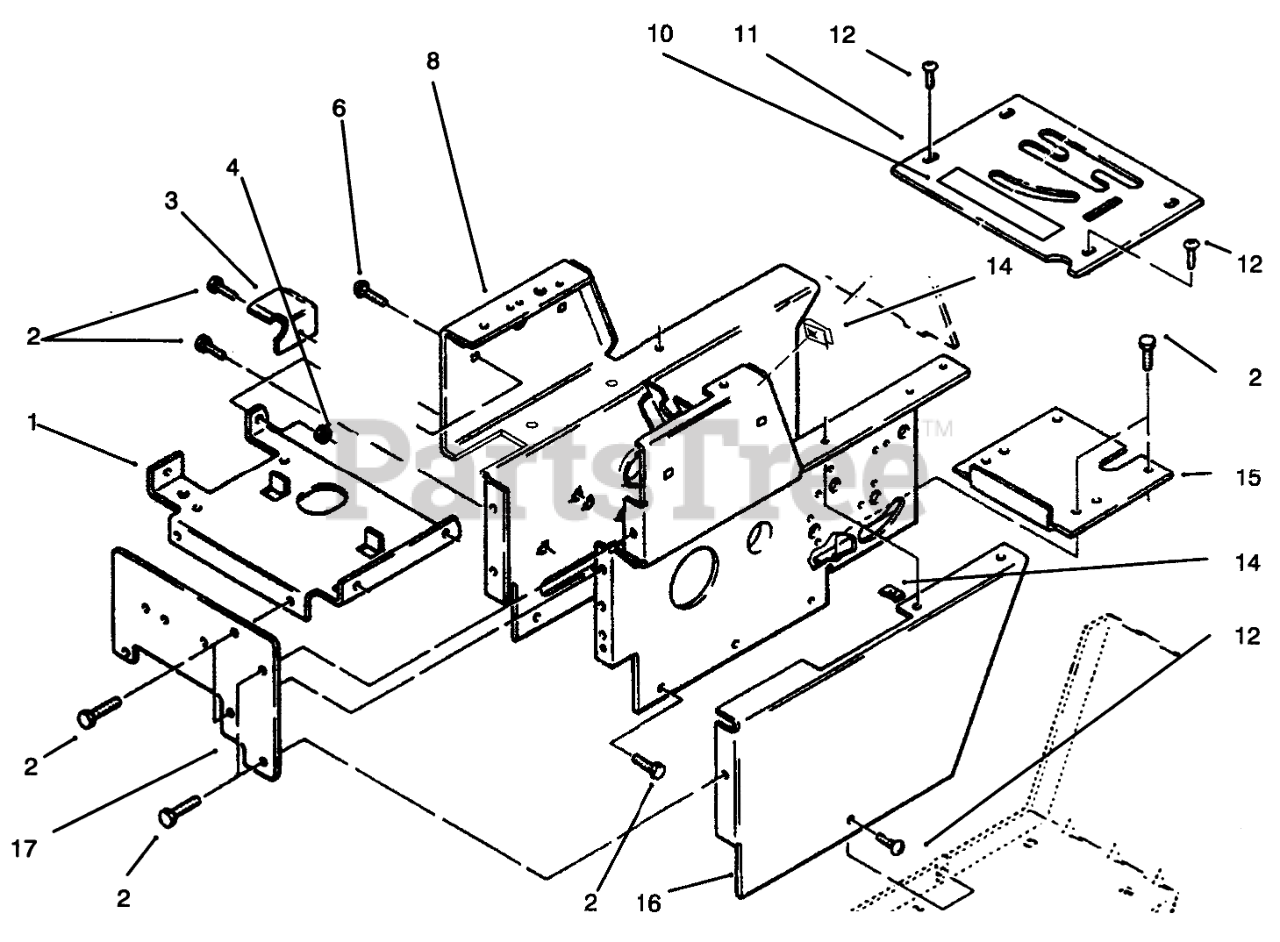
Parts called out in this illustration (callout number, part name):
1	SUPORT-BATERYB
2	Bolt
3	Bracket-Belt
4	Nut
6	BOLT CARR. 5/16X1/2 BK
8	Hoodstand
10	DECAL-DANGER
11	Plate-Shift Cover (Incl. Ref. #10)
12	SCREW-PPH
15	Cover-Dust
16	Cover-Side LH
17	Front Plate
